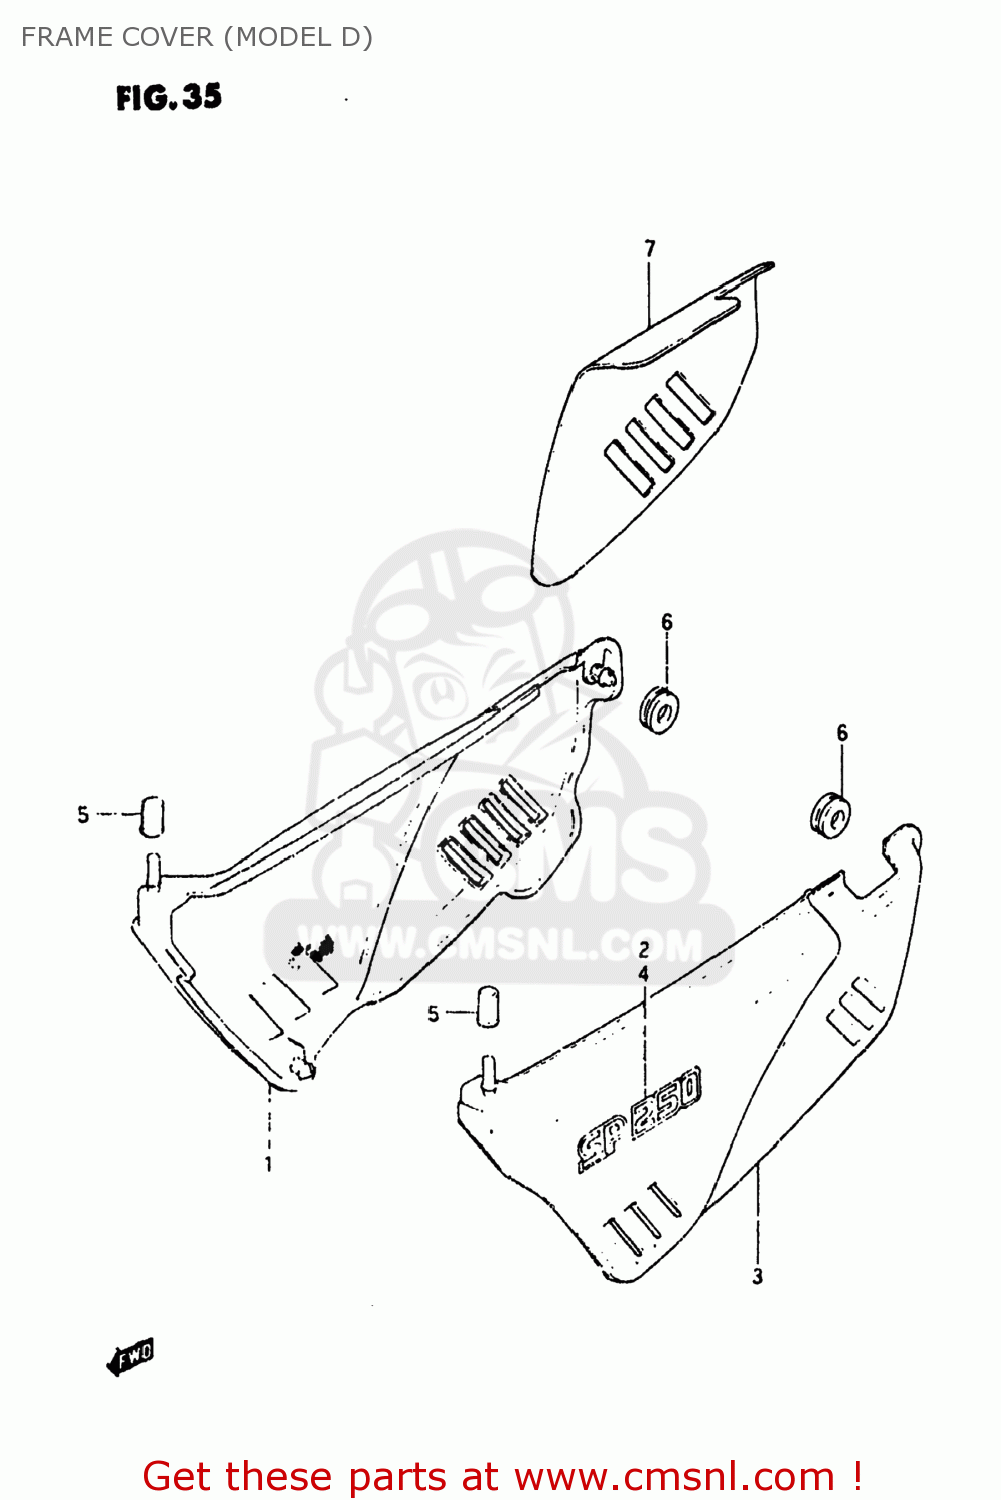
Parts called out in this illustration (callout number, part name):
1	COVER,FRAME,RIGHT
2	EMBLEM
3	COVER,FRAME,LEFT
4	EMBLEM
5	CUSHION
6	CUSHION
7	HEAT SHIELD,FRAME COVER
